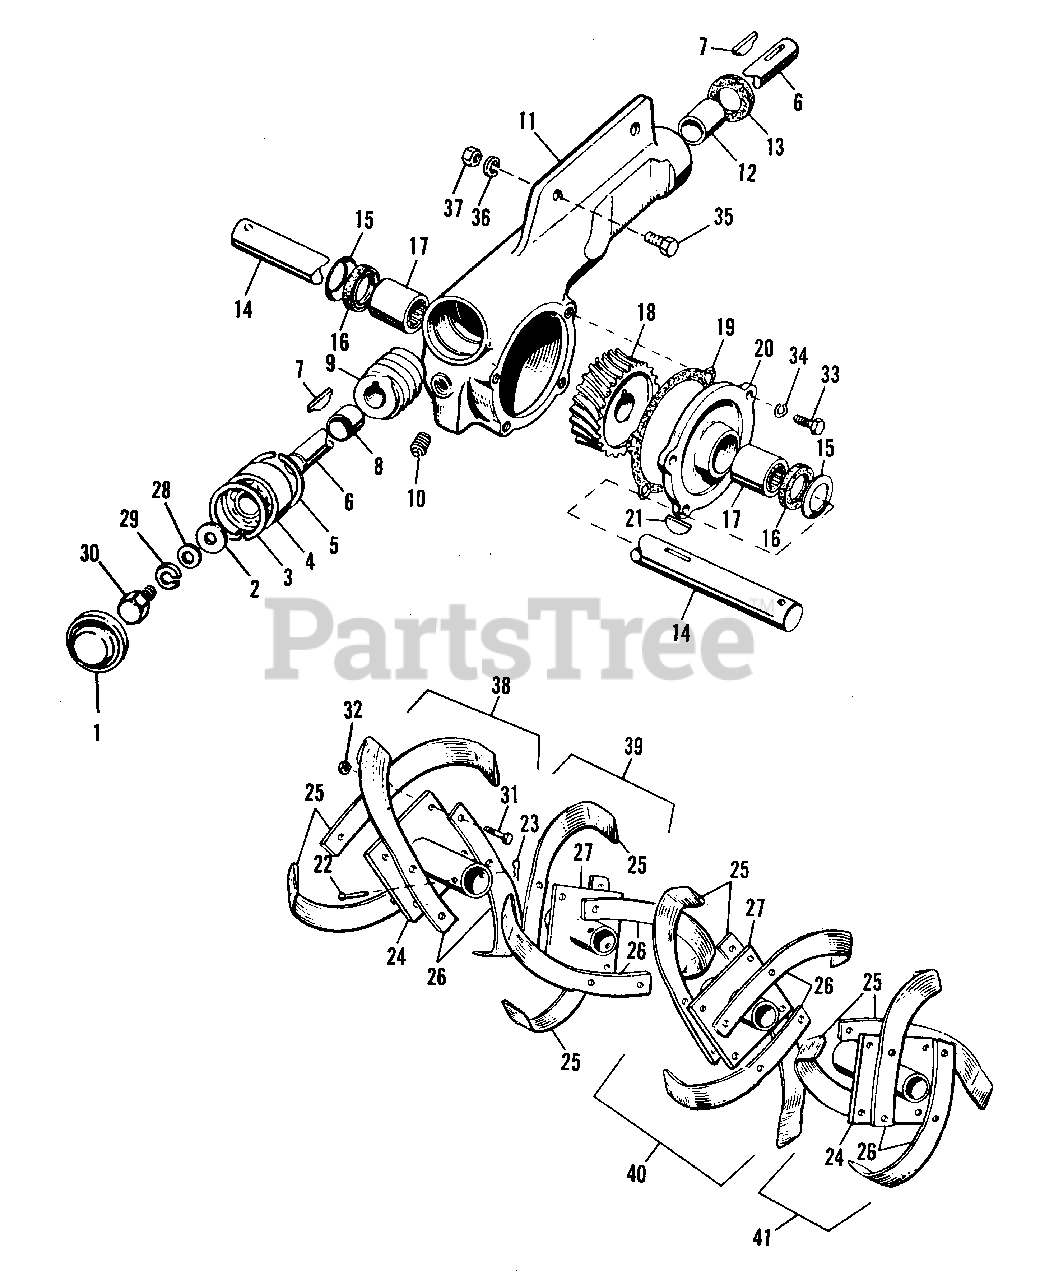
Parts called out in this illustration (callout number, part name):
3	RING, Retaining
4	BEARING, Ball
5	RING, Snap
6	SHAFT, Worm
7	KEY, Hi-Pro #706
10	PLUG, Pipe, 3/8
11	DRIVE HOUSING, Worm
12	BUSHING
14	SHAFT, Worm Gear
17	BEARING, Needle
20	COVER
21	KEY, Woodruff, 1/4-3/4, #91
22	PIN
23	CLIP, Spring
24	PLATE ASSY, Outer Tine (990233 Only)
24	PLATE ASSY, Outer Tine
25	BLADE, L.H. Tine
26	BLADE, R.H. Tine
27	PLATE ASSY, Inner Tine
28	WASHER, Plain, 5/16
29	LOCKWASHER, 5/16
30	CAPSCREW, Hex Hd., 3/8-24 x 1
31	CAPSCREW, Hex Hd., 7/16-20 x 1-1/4
32	NUT, Hex, Full Lock, 7/16-20
33	CAPSCREW, Hex Hd., 1/4-20 x 5/8
34	LOCKWASHER, 1/4
35	CAPSCREW, Hex Hd., 3/8-16 x 3/4
36	LOCKWASHER, 3/8
37	NUT, Hex, Full, 3/8-16
38	TINE ASSY, Outer R.H.
39	TINE ASSY, Inner R.H.
40	TINE ASSY, Inner L.H.
41	TINE ASSY, Outer L.H.
42	WASHER, Thrust
